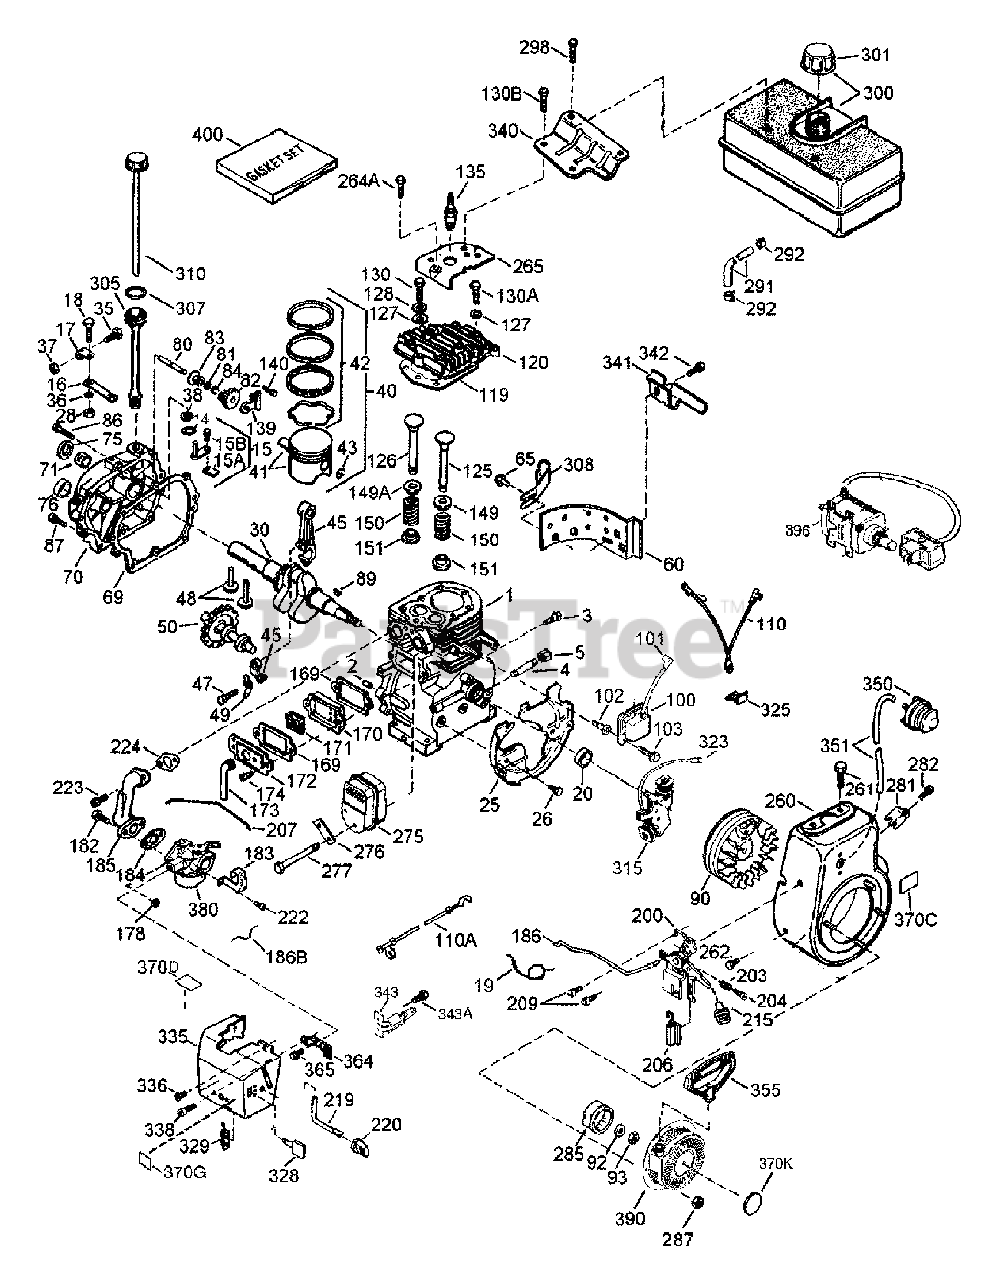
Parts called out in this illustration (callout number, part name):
1	Cylinder
2	Dowel Pin
3	Screw, 1/4-20 x 1/2"
4	Oil Drain Extension
5	Extension Cap
15	Governor Rod
15A	Governor Yoke
15B	Screw, 6-40 x 5/16"
16	Governor Lever
17	Governor Lever Clamp
18	Screw, T-15, 8-32 x 7/16"
19	Throttle Spring
25	Blower Housing Baffle
26	Screw, 1/4-20 x 19/32"
28	Lock Nut, 8-32
30	Crankshaft
35	Screw, 10-32 x 3/4"
36	Lock Washer
37	Lock Nut, 10-32
38	Retaining Ring
40	Piston, Pin & Ring Set (Std.)
40	Piston, Pin & Ring Set (.010" OS)
40	Piston, Pin & Ring Set (.020" OS)
41	Piston & Pin Ass'y. (Std.)
41	Piston & Pin Ass'y. (.010" OS)
41	Piston & Pin Ass'y. (.020" OS)
42	Ring Set (Std.)
42	Ring Set (.010" OS)
42	Ring Set (.020" OS)
43	Piston Pin Retaining Ring
45	Connecting Rod Ass'y.
47	Connecting Rod Bolt
48	Valve Lifter
49	Oil Dipper
50	Camshaft (MCR)
60	Blower Housing Extension
65	Screw, 10-24 x 1/2"
69	Cylinder Cover Gasket
70	Cylinder Cover
71	Crankshaft Bushing
76	Camshaft Seal
80	Governor Shaft
82	Governor Gear Ass'y.
83	Governor Spool
84	Retaining Ring
86	Screw, 1/4-20 x 1-3/16"
87	Screw, 1/4-20 x 1-11/16"
89	Flywheel Key
90	Flywheel (W/Ring Gear)
92	Lock Washer
93	Flywheel Nut
100	Solid State Ignition
101	Spark Plug Cover
102	Solid State Mounting Stud
103	Screw, T-15, 10-24 x 15/16"
110	Ground Wire
110A	Ground Wire
119	Cylinder Head Gasket
120	Cylinder Head
125	Exhaust Valve (Std.)
125	Exhaust Valve (1/32" OS)
126	Intake Valve (Std.)
128	Belleville Washer
130	Screw, 5/16-18 x 1-1/2"
130A	Screw, 5/16-18 x 2"
130B	Screw, 5/16-18 x 39/64"
130C	Screw, 5/16-18 x 1-25/32"
135	Resistor Spark Plug (RJ19LM)
139	Governor Gear Bracket
140	Screw, 10-24 x 1/2"
149	Valve Spring Cap
149A	Valve Spring Cap
150	Valve Spring
151	Valve Spring Keeper
169	Valve Cover Gasket
170	Breather Body
171	Breather Element
172	Valve Cover
173	Breather Tube
174	Screw, 10-24 x 1/2"
178	Nut & Lock Washer, 1/4-28
182	Screw, 1/4-28 x 1"
183	Choke Bracket
184	Carburetor To Intake Pipe Gasket
185	Intake Pipe
186	Governor Link
186B	Choke Spring
200	Control Bracket
203	Compression Spring
204	Screw, T-10, 5-40 x 7/16"
207	Throttle Link
209	Screw, 10-32 x 1/2"
215	Control Knob
219	Choke Rod
220	Choke Knob
222	Screw, 10-32 x 1/2"
223	Screw, T-30, 5/16-18 x 1-3/32"
224	Intake Pipe Gasket
260	Blower Housing
261	Screw, 5/16-18 x 3/4"
262	Screw, T-40, 5/16-24 x 21/32"
264A	Screw, 1/4-20 x 5/8"
265	Cylinder Head Cover
276	Locking Plate
277	Screw, 5/16-18 x 4-3/16"
281	Starter Bubble Cover
282	Screw, 8-32 x 3/8"
285	Starter Cup
287	Nut & Lock Washer, 1/4-28
291	Fuel Line
292	Fuel Line Clamp
298	Screw, 1/4-15 x 3/4"
300	Fuel Tank
301	Fuel Cap
305	Oil Fill Tube
308	Fill Tube Clip
315	Alternator Coil (3/5 Split)
325	Wire Clip
328	Key Switch (Push-In)
335	Carburetor Cover
336	Screw, 10-32 x 1/2"
338	Screw, 10-32 x 3/8"
340	Fuel Tank Bracket
341	Fuel Tank Bracket
342	Screw, 1/4-20 x 19/32"
343	Key Switch Bracket
343A	Screw, 10-32 x 23/64"
350	Primer Ass'y.
351	Primer Line
355	Starter Handle (Mitten Grip)
364	Carburetor Cover Bracket
365	Screw, 8-32 x 27/64"
370C	Primer Decal
370D	Instruction Decal
370G	Instruction Decal
370I	Warning Decal
370K	Starter Decal
380	Carburetor
390	Rewind Starter
396	Electric Starter Motor
400	Gasket Set
